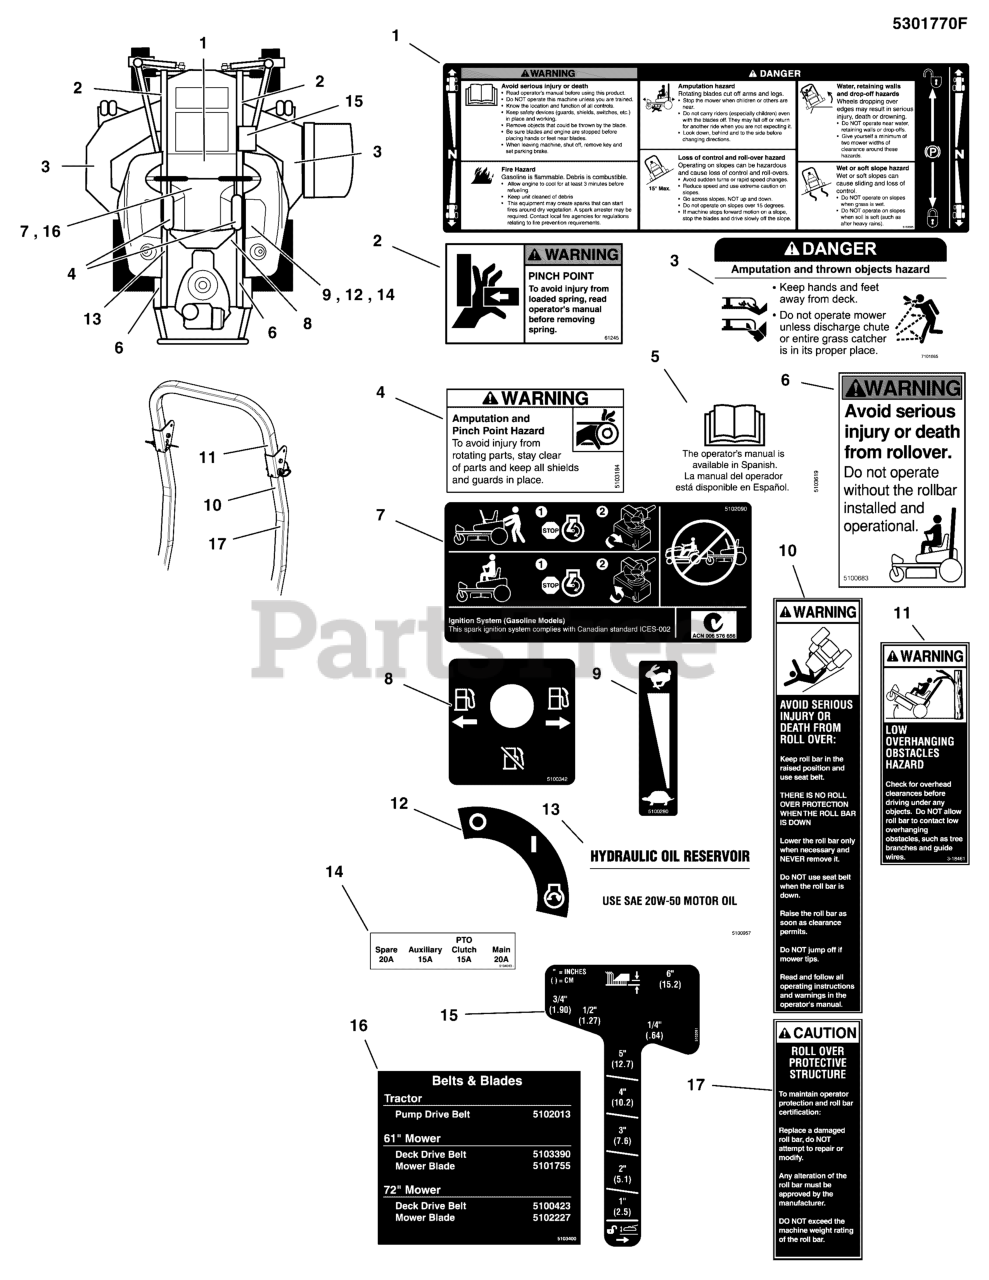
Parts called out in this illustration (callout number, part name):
1	DECAL, MAIN SAFETY
2	DECAL, PINCH POINT
3	DECAL, DANGER DO NOT OPERATE W/O DEFLECT
4	DECAL, WARNING, HAND IN BELT, ENG ONLY
5	DECAL, MANUAL AVAIL IN SPANISH
6	DECAL, WARNING, ROLL BAR
7	DECAL, TRANSAXLE RELEASE, S200XT
8	DECAL, FUEL VALVE
9	DECAL, THROTTLE CONTROL
10	DECAL, WARNING, FOLDING ROPS
11	DECAL, WARNING & CAUTION, ROPS
12	DECAL, IGNITION SWITCH
13	DECAL, HYDRAULIC OIL, SAE 20W50
14	DECAL, FUSE LOCATION, IS2100
15	DECAL, DECK HEIGHT, 1-1/2 TO 6, S200XT
16	DECAL, BELT & BLADE, S200XT
17	DECAL, CAUTION. FOLDING ROPS
